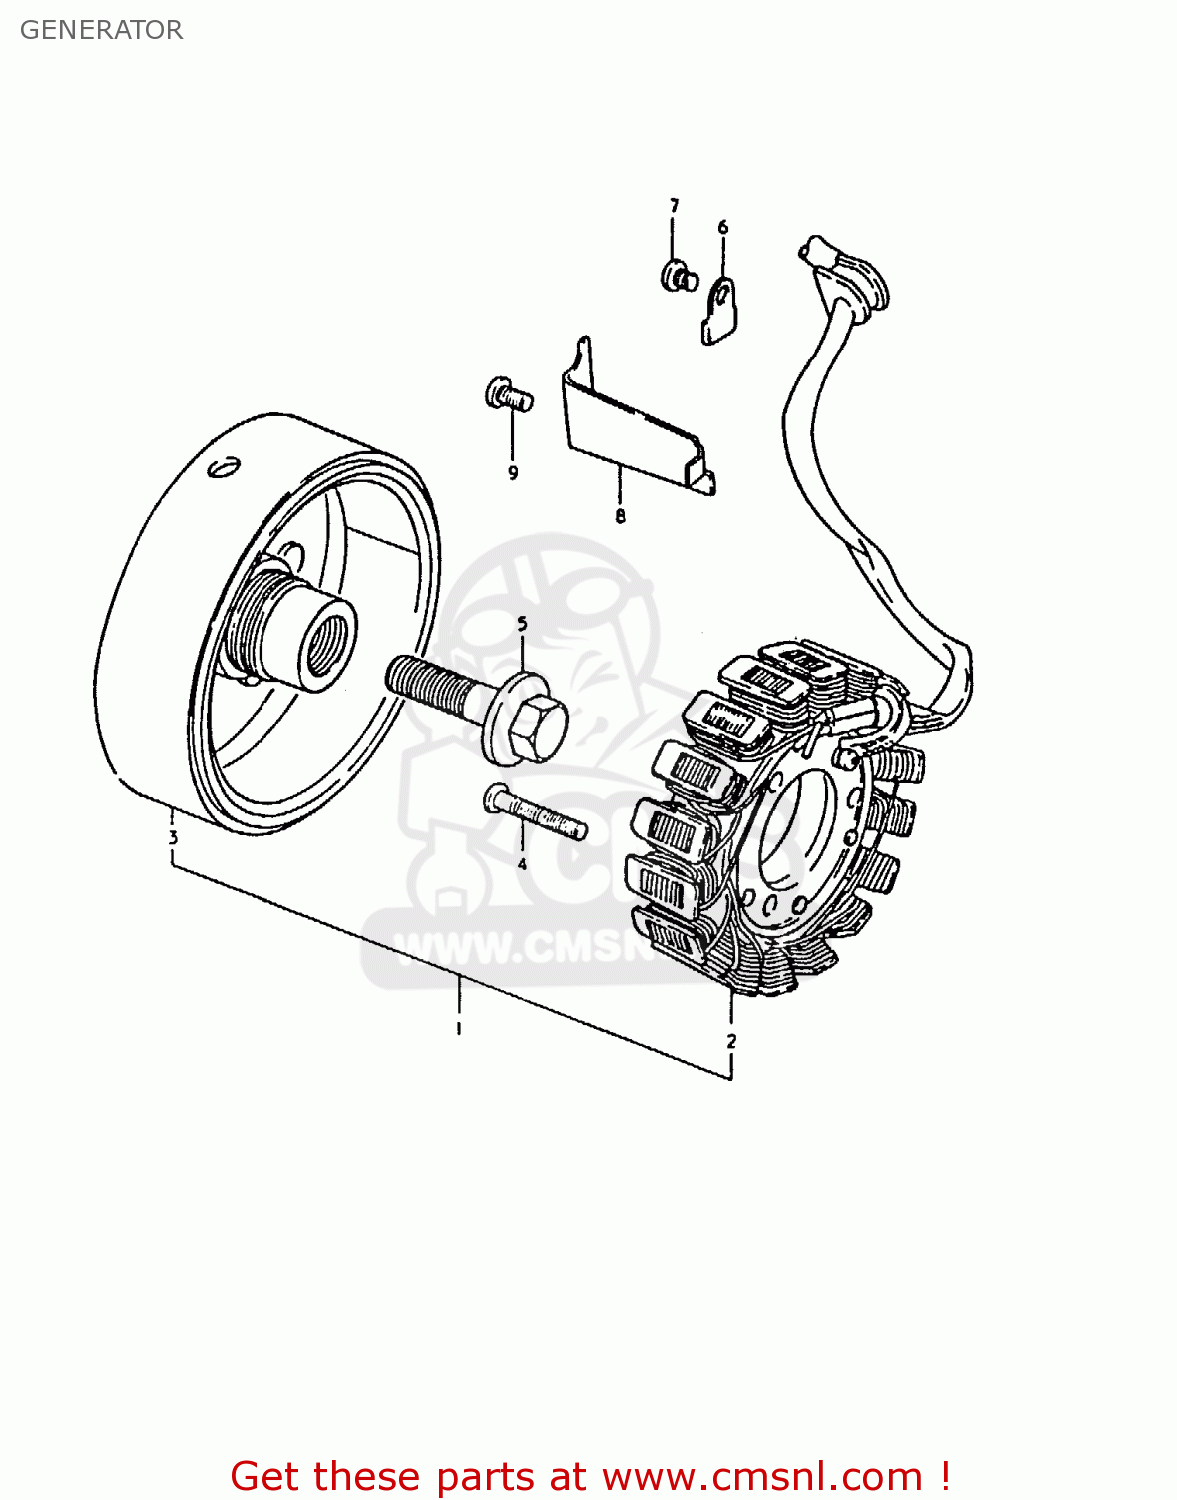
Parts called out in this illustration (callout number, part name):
1	GENERATOR ASSEMBLY
2	STATOR ASSEMBLY
3	ROTOR ASSEMBLY
4	SCREW 6X30
5	BOLT
6	CLAMP,GENERATOR LEAD WIRE
7	SCREW
8	CLAMP,GENERATOR LEAD WIRE
9	SCREW
